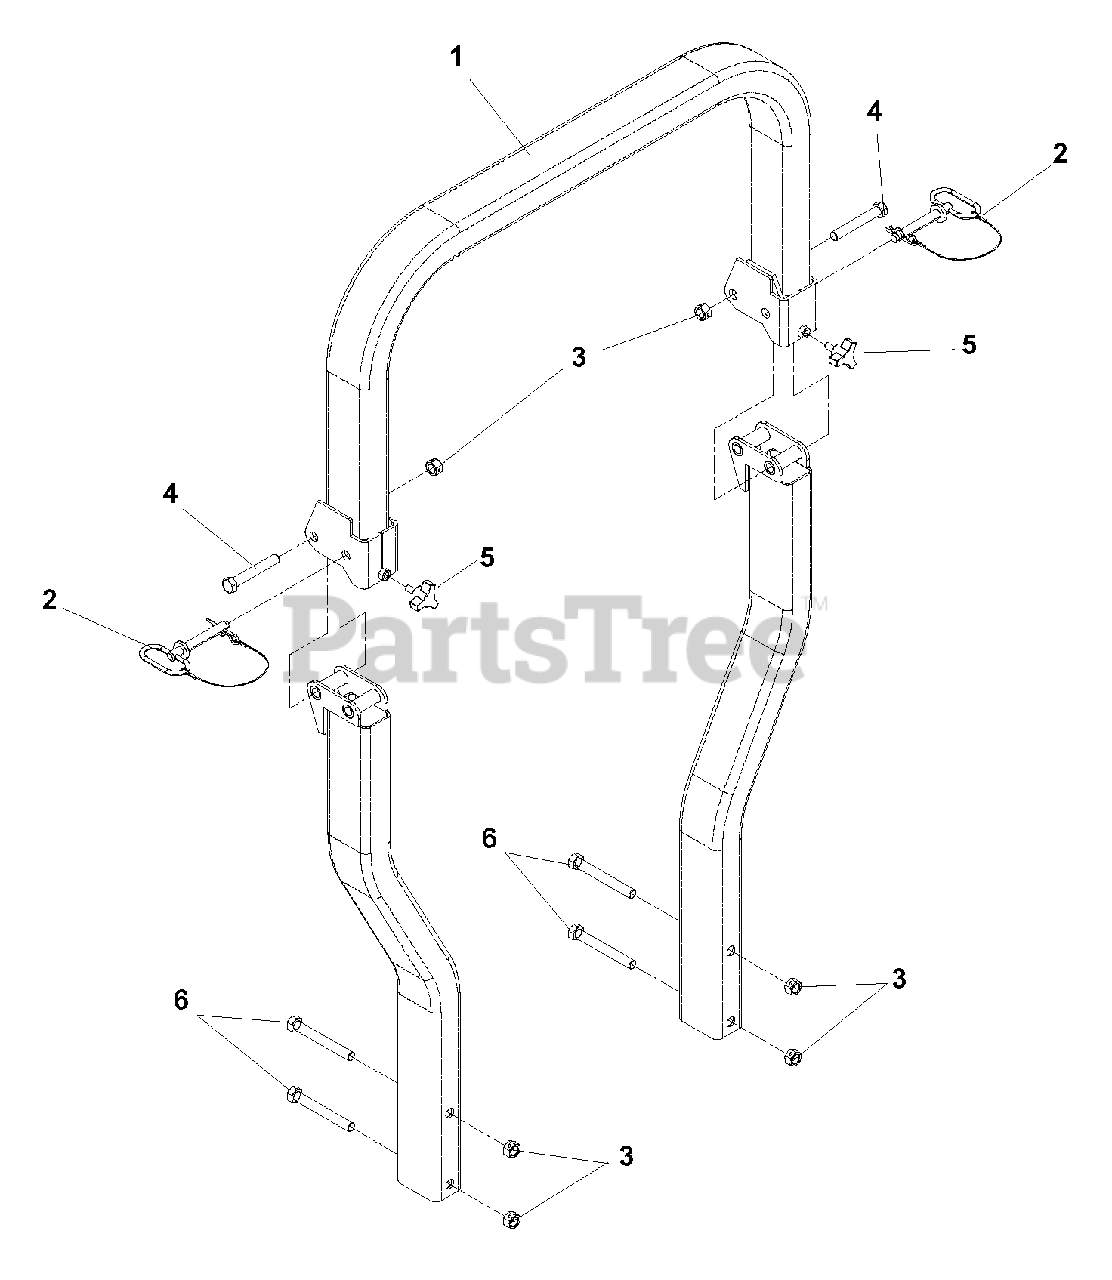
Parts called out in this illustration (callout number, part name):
1	ROPS W/SEAT BELT,COMPLETE
2	PIN W/LANYARD, 1/2"
3	NUT, 1/2 -13, CENTERLOCK
4	HCS, 1/2C x 3 1/4, GR5
5	KNOB W/STUD
6	HCS, 1/2C x 4, GR5
